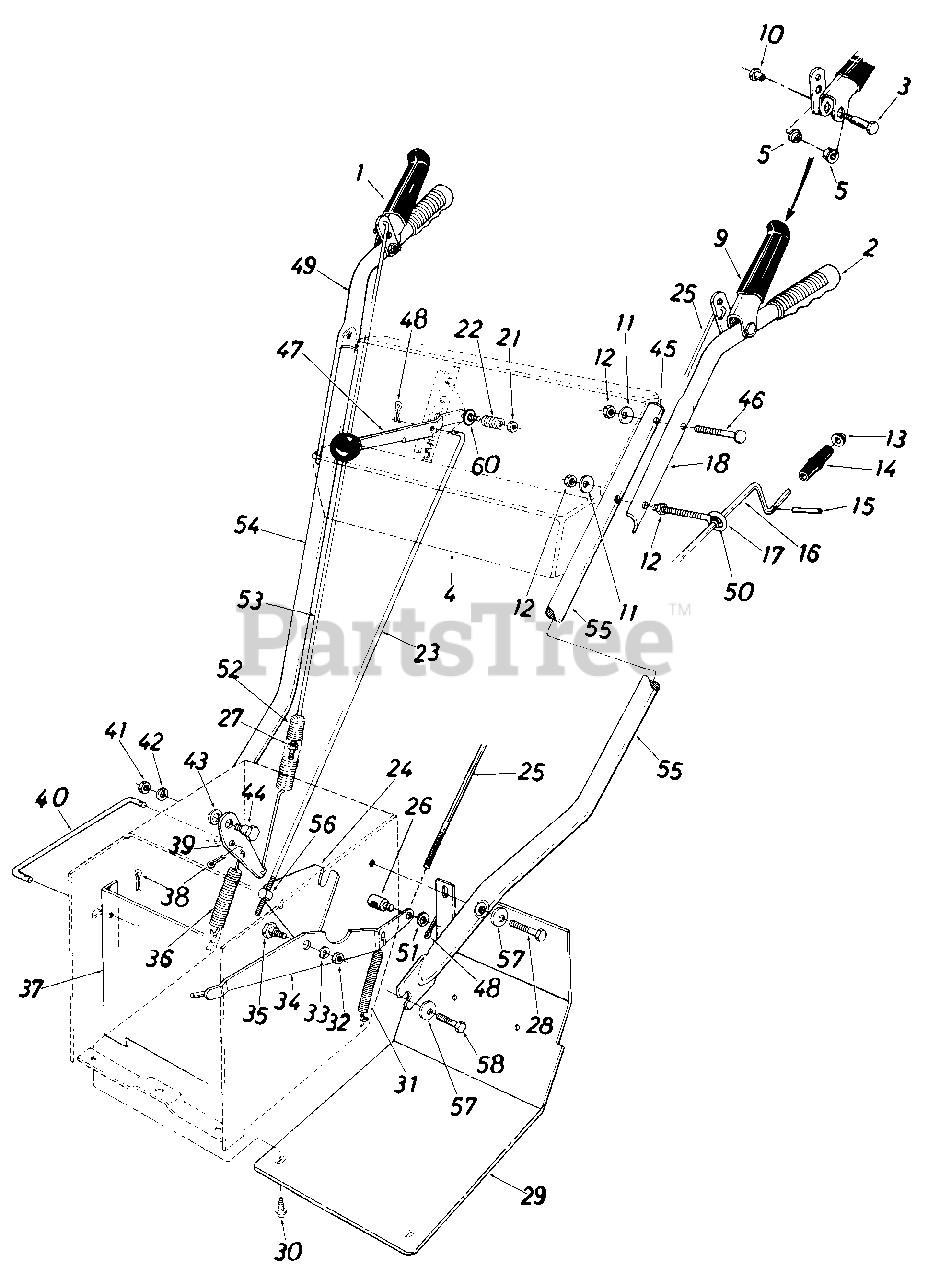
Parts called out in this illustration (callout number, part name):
1	Clutch Grip Ass'y.-R.H.
2	Grip
3	Shoulder Bolt .374 Dia. x 1.53" Lg.
4	Handle Panel Ass'y.
5	Hex Flange Plastic Bearing .380" I.D.
9	Clutch Grip Ass'y.-L.H.
10	Shoulder Nut 1/4-20 Thd.
11	Bell-Wash. .34" I.D. x .88" O.D.
12	Hex Nut 5/16-18 Thd.
13	Push Nut 3/8" Rod
14	Knob 3/8" Rod
15	Roll Pin .12 Dia. X .63" Lg.
16	Chute Crank Ass'y. 39" Lg.
17	Eye Bolt 5/16-18 x 5.0" Lg.
18	Upper Handle-L.H.
21	Hex Ins. Jam L-Nut 3/8-24 Thd .
22	Compression Spring .50" O.D. x .88" Lg.
23	Shifting Rod 5/16" x 32.50" Lg.
24	Shifting Linkage Bracket
25	Lockout Rod .214" Dia. x 36.0" Lg.
26	Adjustment Ferrule 1/4-20
27	Hex Ins. L-Nut 1/4-20 Thd.
28	Hex Bolt 3/8-16 x 2.00" Lg.
29	Frame Cover
30	Hex Wash. Self-Tap Scr. 1/4-20 x .50" Lg.
31	Extension Spring .38" O.D. x 3.25" Lg.
32	Hex Jam Nut 3/8-16 Thd.
33	L-Wash. 3/8" I.D.*
34	Auger Clutch Bracket Ass'y.
35	Shld. Bolt .625" Dia. x .170
36	Extension Spring .75" O.D. x 4.31 " Lg.
37	Drive Pulley Support Brkt. Ass'y.
38	Cotter Pin 3/32" Dia. x .75"-Lg.*
39	Drive Clutch Bracket
40	Drive Clutch Rod
41	Hex Jam Nut 3/8-16 Thd.
42	L-Wash. 3/8" I.D.*
43	Fl-Wash. .34" I.D. x .75" O.D.
44	Shld. Bolt .625" Dia. x .170
45	Plastic Plug
46	Carriage Bolt 5/16-18 x 2.0" Lg.
47	Shift Handle Ass'y.
48	Int. Cotter Pin 5/16" Dia.
49	Upper Handle-R.H.
50	Plastic Bushing
52	Extension Spring .75" O.D. x 5.00" Lg.
53	Lockout Rod .214" Dia. x 32" Lg.
54	Lower Handle-R.H.
55	Lower Handle-L.H.
56	Adjustment Ferrule
57	Bell-Wash. .40" I.D. x .88" O.D.
58	Hex Wash. Self-Tap Scr. 3/8-16 x .75" Lg.
60	Bell-Wash. .40" I.D. x .88" O.D.
